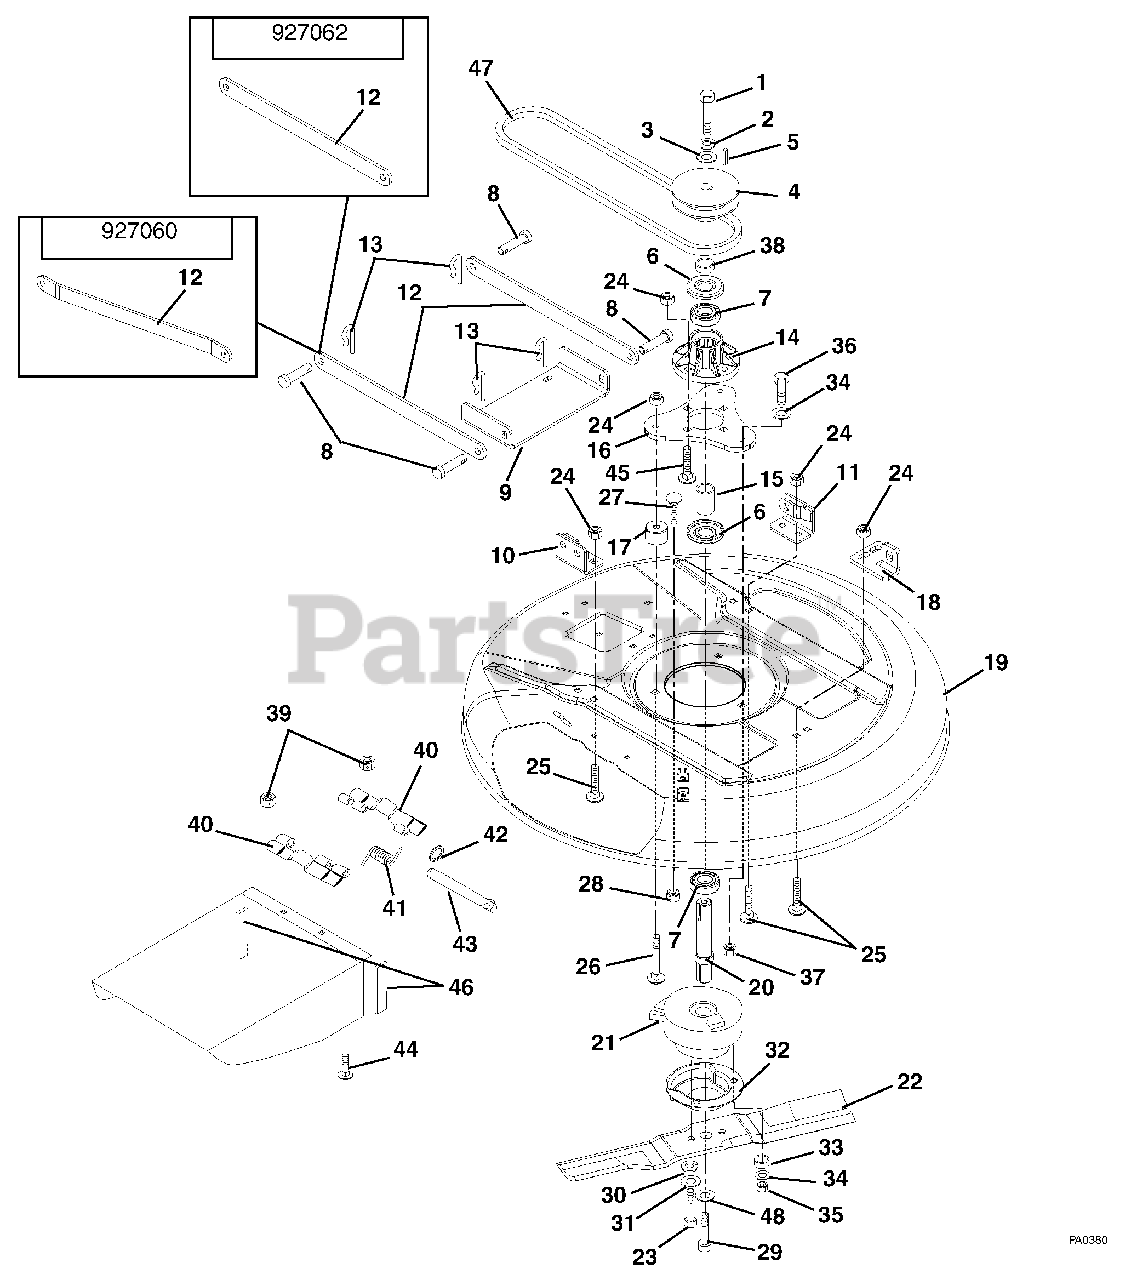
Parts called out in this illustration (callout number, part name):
1	Bolt-Hex .38-16 x 1.00 Grade 8 with Epoxy Patch
2	Washer, Locking .375 x .115 Heavy
3	Washer, Flat Steel .406 x 1.375 x .135
4	Pulley, 28" Deck Input
4	Pulley, 32" Deck Input
5	Key, Square .25 x .38 x .25
6	Bearing, Slinger
7	Bearing, Ball 1.00 x 2.00 x .56
8	Pin, Clevis .494 x 1.00
9	Bracket, Rear Hanger 28"(060)
9	Bracket, Rear Hanger 32" (062)
10	Bracket, Deck Link Right Hand (060)
10	Bracket, Deck Link Right Hand (062)
11	Weldment, Deck Link Right Hand (060)
11	Weldment, Deck Link Left Hand (062)
12	Link-Stabilizer (Right Hand Only) (060)
12	Link Stabilizer (060)
12	Link Stabilizer (062)
13	Clip, Spring
14	Assembly, Spindle Housing
15	Spacer, 1.00 x 1.25 x 1.60
16	Spindle, Mount Plate
17	Spacer, Mounting Plate
18	Bracket, Front Lift Hanger (060)
18	Bracket, Front Lift Hanger (062)
19	Deck 32"
20	Shaft, 32" Input
21	Clutch Kit (061)
22	Blade, 28" Mower
22	Blade, 32" Mower
23	Bolt, Hex M10 x 1.25 x 30
24	Nut, Locking-Top-Flange .38-16
25	Bolt-Round Head Square Neck .38-16 x .75 Grade 5
26	Bolt-Round Head Square Neck .38-16 x 2.25 Grade 5
27	Bolt-Round Head Square Neck .31-18 x 1.50 Grade 5
28	Nut, Spin Lock Flange .312-18
29	Bolt, Button Head .50 x 1.25-20
30	Washer, Locking Metric 10 MM
31	Washer, Flat Steel .406 x 1.00 x .188
32	Shield, Debris
33	Bushing, Bronze .75 I.D. x .88 O.D. x .50 Long
34	Washer, Flat Steel .38 x .875 x .083
35	Nut-Locking-Nylon .38-16
36	Bolt-Hex .38-16 x 3.00 Grade 5
37	Nut-Flange .375-16
38	Spacer Steel 1.01 x 1.38 x .509
39	Nut-Locking-Center .25-20
40	Hinge Plate
41	Spring-Torsion .09 x .37 x .63
42	Ring-Retaining-External .312 x .025
44	Bolt-Round Head Square Neck .25-20 x .75 Grade 5
45	Bolt-Round Head Square Neck .38-16 x 1.25 Grade 5
46	Trim Bulk 0125
47	Belt, PTO (060)
47	Belt, PTO (062 SN = 000140 and up)
48	Washer, Flat Steel .50 x 1.75 x .187
